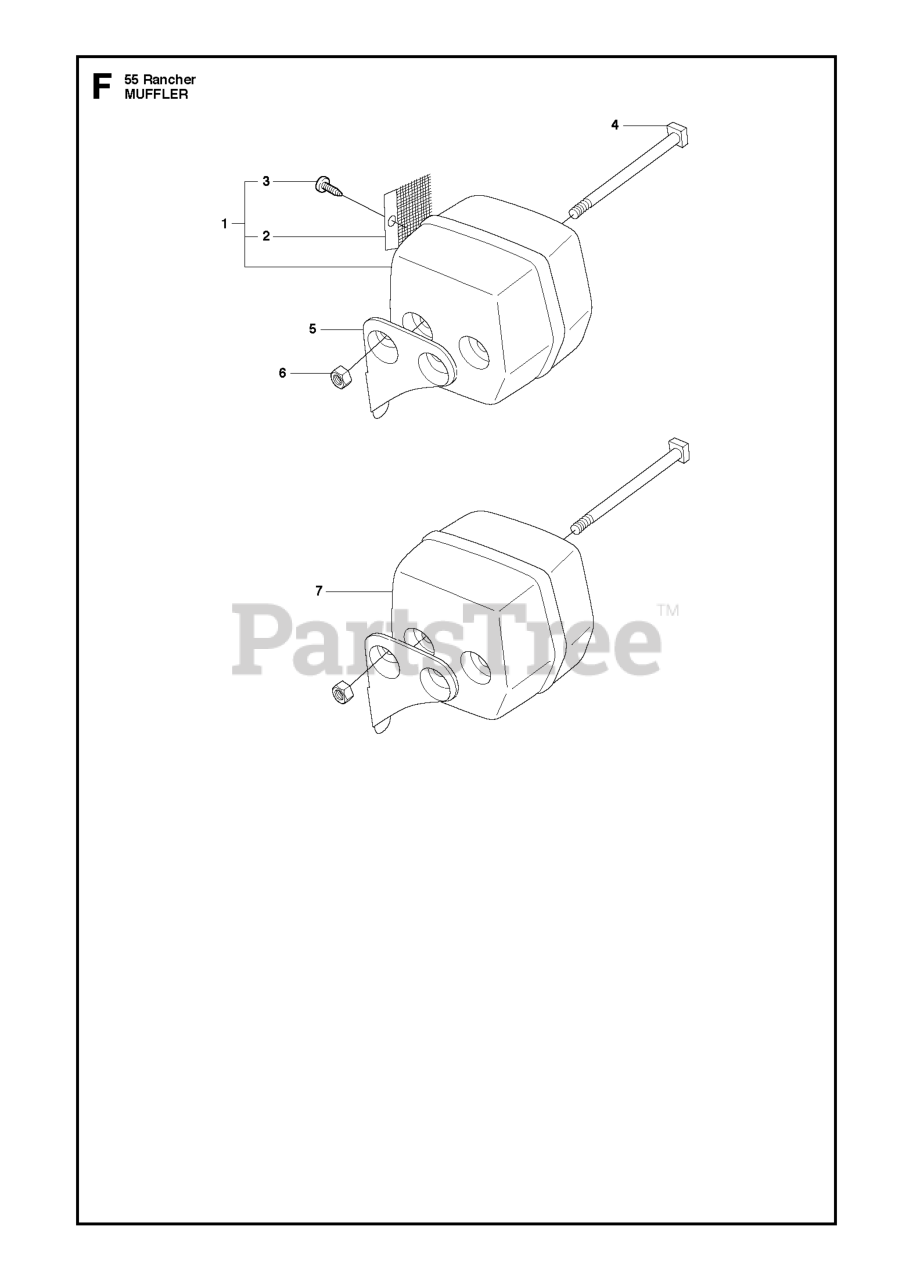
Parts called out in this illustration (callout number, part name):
1	MUFFLER - USA
4	SQUARE HEAD SCREW 5X80
5	SILENCER BRACKET
7	MUFFLER
